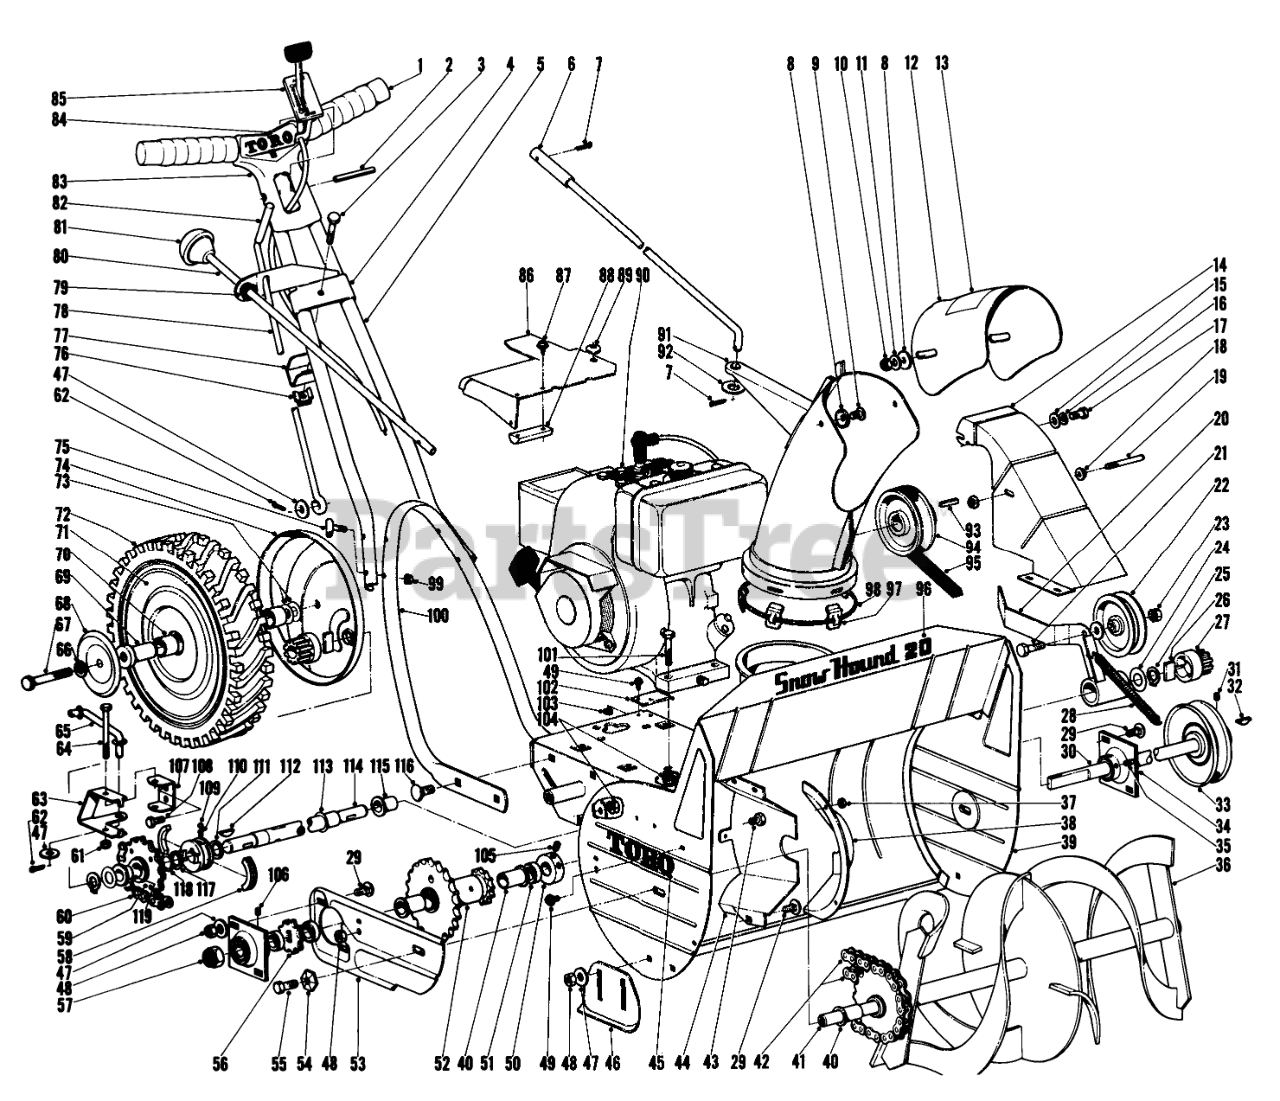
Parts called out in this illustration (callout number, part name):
1	Handle Clip
2	PIN-ROLL
3	SCREW-HH
4	Bracket-Control
5	Handle Arm, Upper W.A.
6	Rod-Chute
7	PIN-COTTER
8	Washer
9	SCREW-PPH
10	Nut
11	WASHER-FLAT
12	Deflector
13	Decal
15	WASHER-FLAT
16	WASHER-LOCK
17	SCREW-HH
18	NUT-HF
19	Guide Pin
20	Belt Tightener
21	SCREW-HH
22	PULLEY B
24	Washer
25	Snap Ring
26	RATCHET DOG
27	Pinion Kit
28	Spring, Tension
29	Bolt
30	Drive Shaft
31	SCREW-SET, HSH
32	KEY-WOODRUFF
33	Pulley
34	Bushing Flange Mounted
35	SCREW-SQH
36	Rotor Incl. Ref. #44
37	NUT-LOCK, NI
38	Guard-Rotor Chain
39	Frame Incl. Ref. #72
40	Bushing
41	ROTOR SHAFT
42	Chain
43	SCREW-HH
44	Guard, Chain
45	Decal
46	Skid
47	WASHER-FLAT
48	Nut
49	SCREW-SHWH
50	Collar
51	COSHAFT SPACER
52	Sprocket (Incl. Ref. 7)
53	Support-Bearing
54	LOCKWASHER-PYRAMID
55	SCREW-HH
56	Sprocket
57	NUT-LOCK, NI
59	Drive Sprocket Assembly
60	Chain
61	Nut
62	PIN-COTTER
63	Fork Shift
64	SCREW-HH
65	Link Shift
66	WASHER-LOCK
67	SCREW-HH
68	Hub Cap
69	Spindle Wheel
70	BUSHING
71	Wheel Incl. Ref. #97
73	WASHER
74	Wheel Cover
77	Strap, Clamp
78	Control Rod Traction
79	Grommet
80	Control Rod Upper Chute
83	Cover Plate
84	Decal
85	Control, Throttle Assy.
86	Chain Guard
87	10-16 X 3/8 THDG SCREW
88	Chain Guide
89	Washer
90	Engine
91	Chute
92	WASHER-FLAT
93	KEY-SQUARE
94	Pulley
96	Decal
98	Garter Spring
99	NUT-KEPS
100	Handle, Lower
101	SCREW-HH
102	Lock Bracket
103	NUT-KEPS
104	Locknut
105	SCREW-HSH
106	SCREW-SET, HSH
107	Pivot Support
108	SCREW-HH
109	BALL-STEEL
110	Spring
111	5/8X039 EX HD RING
112	KEY-WOODRUFF
113	Washer
114	Drive Shaft
115	BUSHING
116	BOLT-CARR
117	Sliding Jaw
118	Thrust Washer
119	BUSHING-FLANGE
